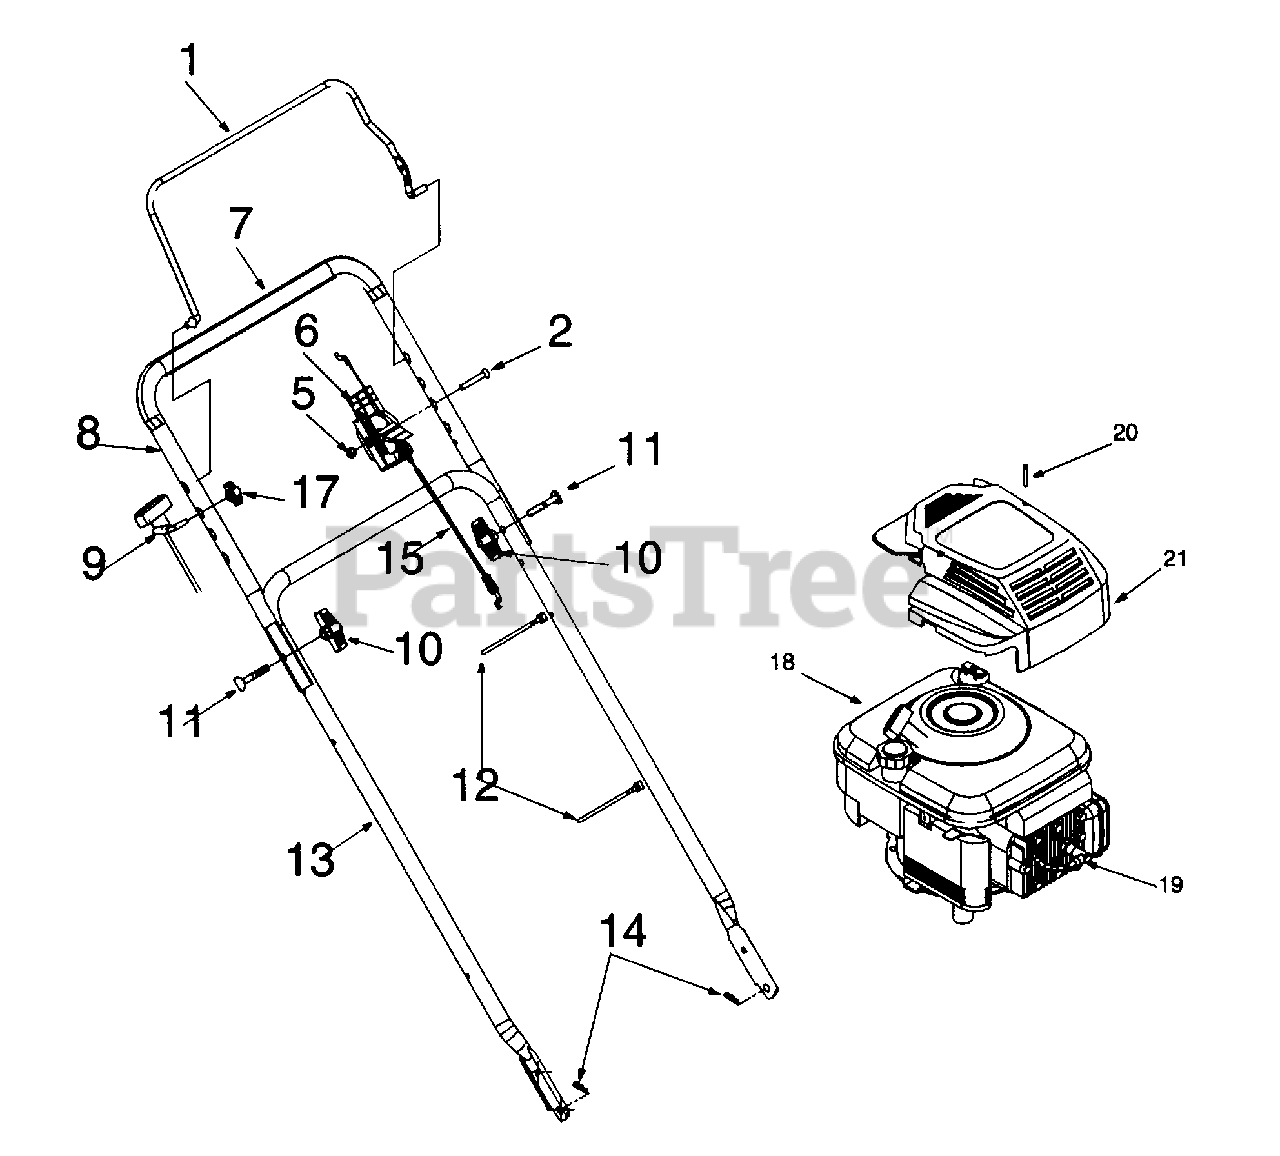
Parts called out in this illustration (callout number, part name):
1	Control Handle Ass'y.
2	Oval C-Sunk Screw
5	Hex Lock Nut
6	Control Housing
7	Foam Grip
10	Hand Knob
11	Carriage Bolt
12	Cable Tie
14	Hairpin Clip
15	Control Cable 40.5" Lg.
17	Handle Knob
18	Engine
19	Spark Plug Boot
20	Hi-Low Screw
21	Engine Shroud
